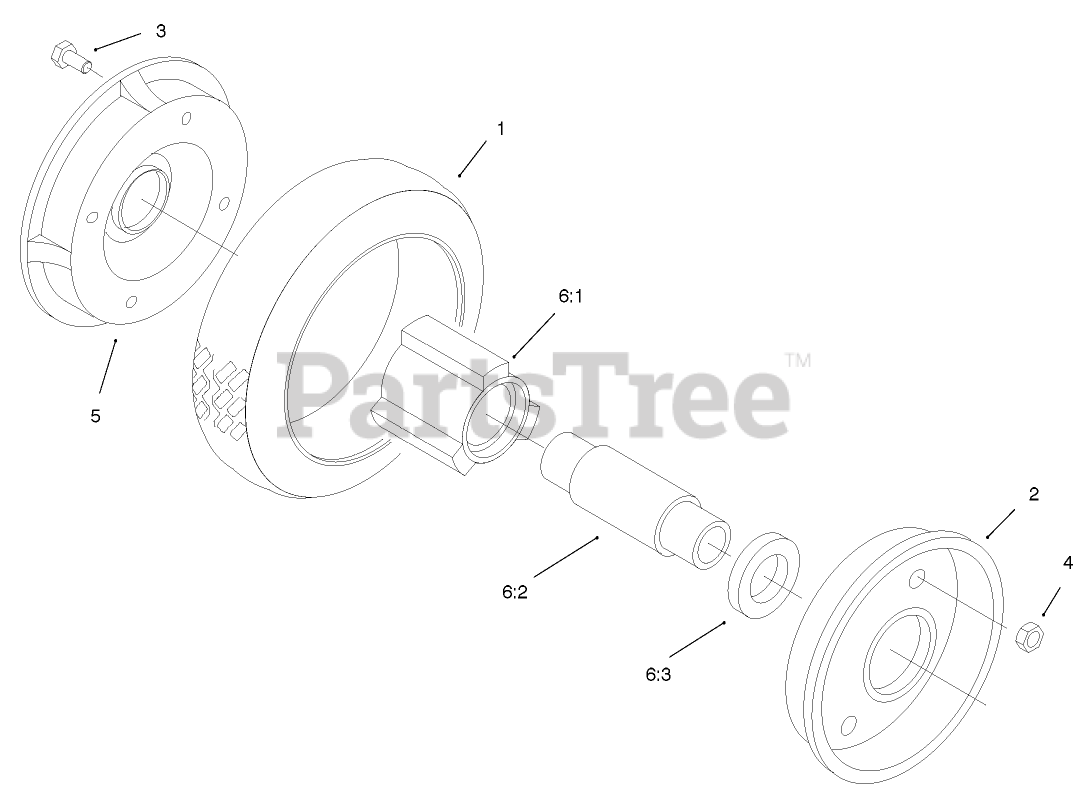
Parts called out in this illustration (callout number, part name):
3	SCREW-HH
4	NUT-LOCK, NI
6	Hub and Bearing ASM
6:1	HUB-BEARING
6:2	SPACER-BEARING
6:3	BEARING-WHEEL
